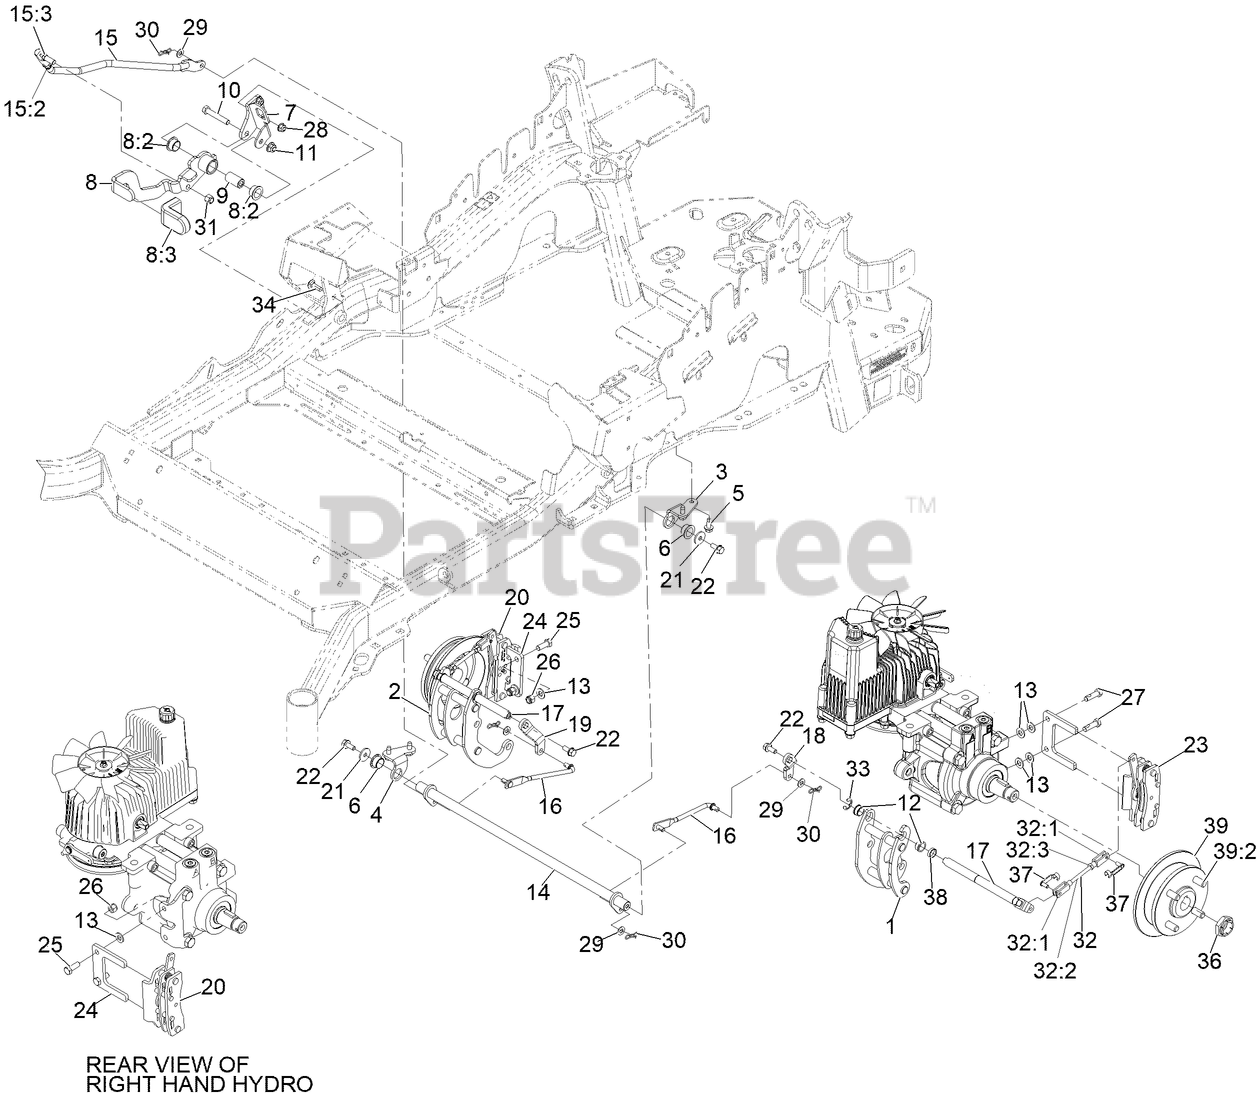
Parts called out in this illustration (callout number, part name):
1	MOUNT-BELLCRANK, LH
2	MOUNT-BELLCRANK, RH
3	MOUNT-PIVOT, LH
4	MOUNT-PIVOT, RH
5	SCREW-HWHTF
6	BUSHING-FLANGE
7	BRACKET-MOUNT
8	BRAKE LEVER ASM W/GRIP M-R
8:2	BUSHING-FLANGE
8:3	GRIP-LEVER
9	HANDLE-PIVOT, BRAKE
10	SCREW-HH
11	NUT-HF, NI
12	BUSHING
13	WASHER-FLAT
14	SHAFT-CROSS
15	ASM, FRONT LINKAGE
15:2	END-TIE ROD, RH
15:3	NUT-HJ
16	MID-LINK, SHORT
17	BELLCRANK
18	ARM-INNER, LH
19	ARM-INNER, RH
20	CALIPER-BRAKE, RH
21	WASHER-FLAT
22	SCREW-HHF
23	CALIPER-BRAKE, LH
24	PLATE-MOUNT, BRAKE
25	SCREW-HH,
26	NUT-LOCK
27	SCREW-HH, PATCH,
28	NUT-HF, NI
29	WASHER-PLAIN
30	PIN-COTTER, LOCKING
31	NUT-LOCK
32	REAR LINKAGE ASM
32:2	LINKAGE, REAR
32:3	NUT-JAM
33	E-RING
34	BOLT-CARR
36	LOCKNUT
37	PIN-CLEVIS, SPRING
38	SPACER
39	WHEEL HUB ASM
39:2	STUD-WHEEL
